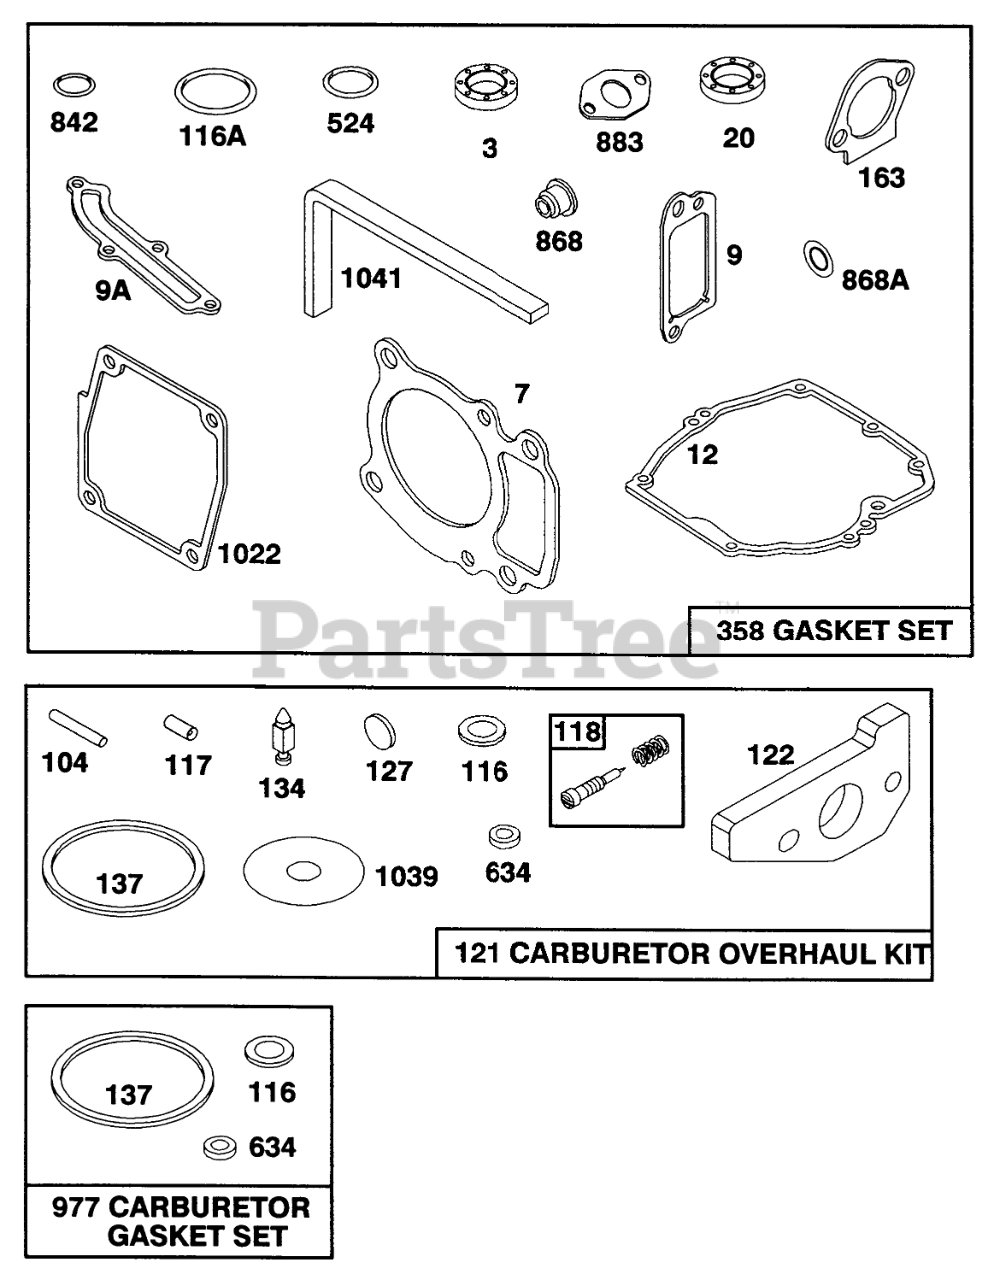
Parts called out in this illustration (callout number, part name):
3	SEAL - OIL
7	CYLINDER HEAD GASKET
9	Gasket-Breather
9A	GASKET-BREATHER
12	ENGINE BASE GASKET
20	SEAL-OIL
104	FLOAT HINGE PIN
116	SEALING GASKET
116A	O RING SEAL
118	VALVE KIT - NEEDLE
121	CARBURATOR OVERHAUL KIT
122	ADAPTER ASSEMBLY
134	Valve-Float (Includes Seat)
137	FLOAT BOWL GASKET
163	AIR CLEANER GASKET
358	GASKET SET
524	O-RING
634	SEAL WASHER
842	O-RING
868	SealAssy-Valve
868A	Seal-Valve
883	EXHAUST GASKET
977	CARBURATOR GASKET SET
1022	ROCKER COVER GASKET
1039	FLOAT LIMITER
1041	SEAL - FOAM
